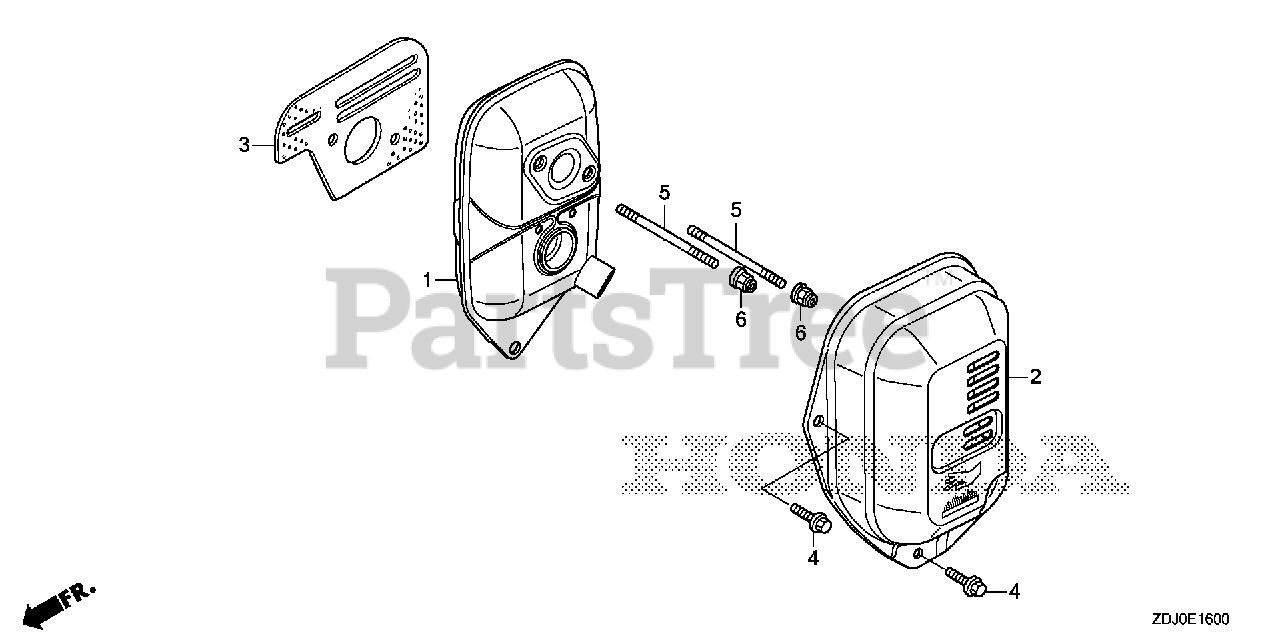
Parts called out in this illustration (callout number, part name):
1	MUFFLER (RAMMER)
2	PROTECTOR, MUFFLER (RAMMER)
3	GASKET, MUFFLER
4	BOLT, FLANGE (6X14)
5	BOLT, STUD (6X56.5)
6	NUT, SELF-LOCK (6MM)
